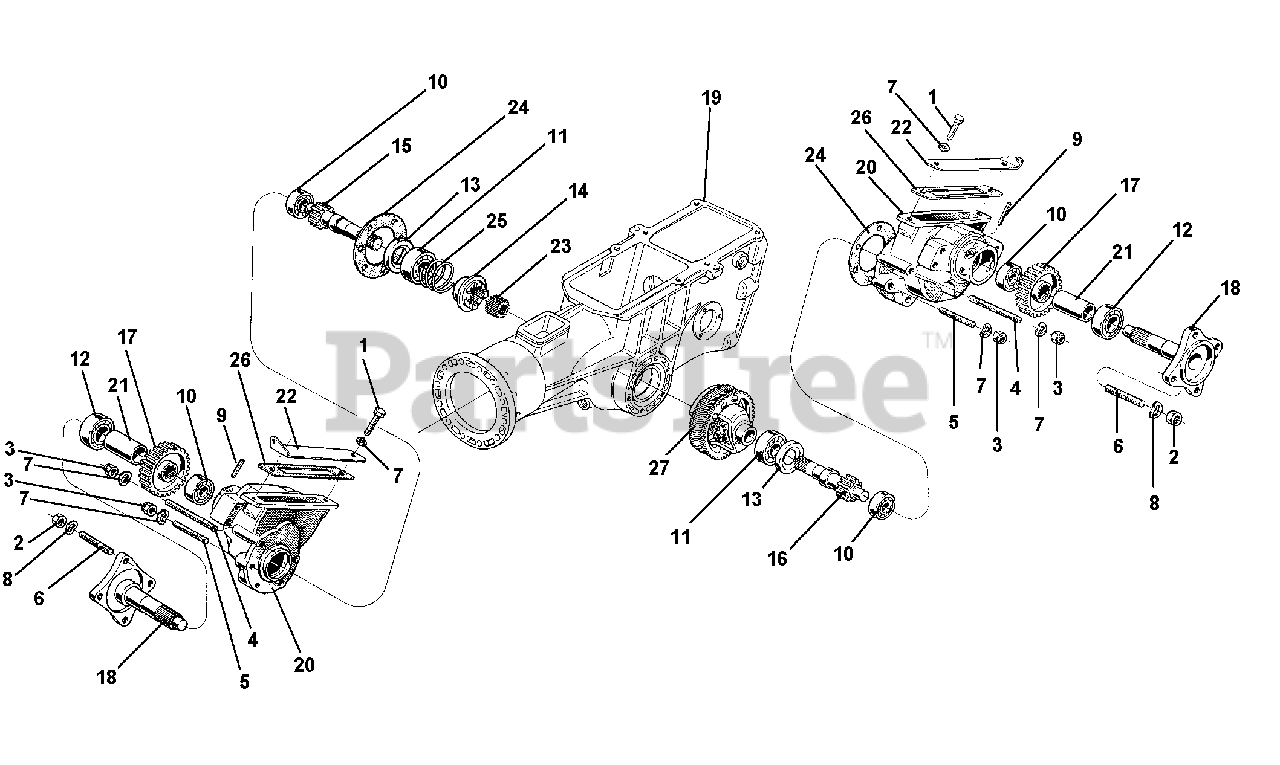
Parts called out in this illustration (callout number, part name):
1	SCREW M8 X 20
3	NUT, SELF LOCKING M8
6	STUD M10 X 40 X 22 X 14
7	WASHER, LOCK 8.4
8	WASHER, LOCK 10.5
9	PIN 4 X 45 SPIRAL
10	BEARING 17 X 40 X 12 6203
11	BEARING 20 X 52 X 15 6304
15	RIGHT SHAFT
17	REDUCTION UNIT GEAR
18	DRIVE SHAFT 745
19	GEARBOX 745 / 606-605
20	REDUCTION UNIT CASE
23	SPACER FOR DIFFERENTIAL
24	JOINT GASKET
26	COVER GASKET
27	DIFFERENTIAL
